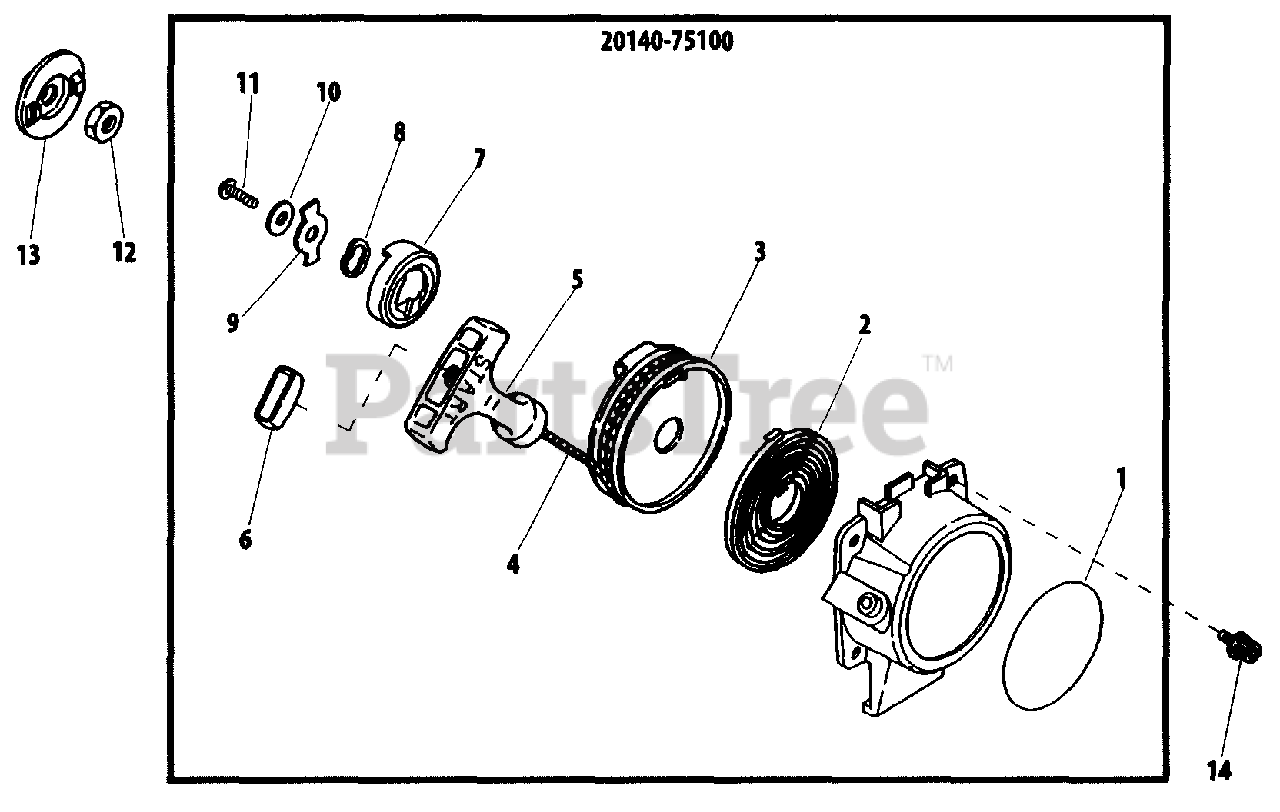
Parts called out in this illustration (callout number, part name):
1	NAMEPLATE
2	SPRING
3	REEL, ROPE
4	ROPE, STARTER
5	GRIP, STARTER
6	RETAINER, ROPE
7	RATCHET
8	WASHER - WAVE
9	RETAINER
10	WASHER
12	NUT - 8
13	REEL, ROPE
14	SCREW - 4X12
20140-75100	STARTER ASSY
